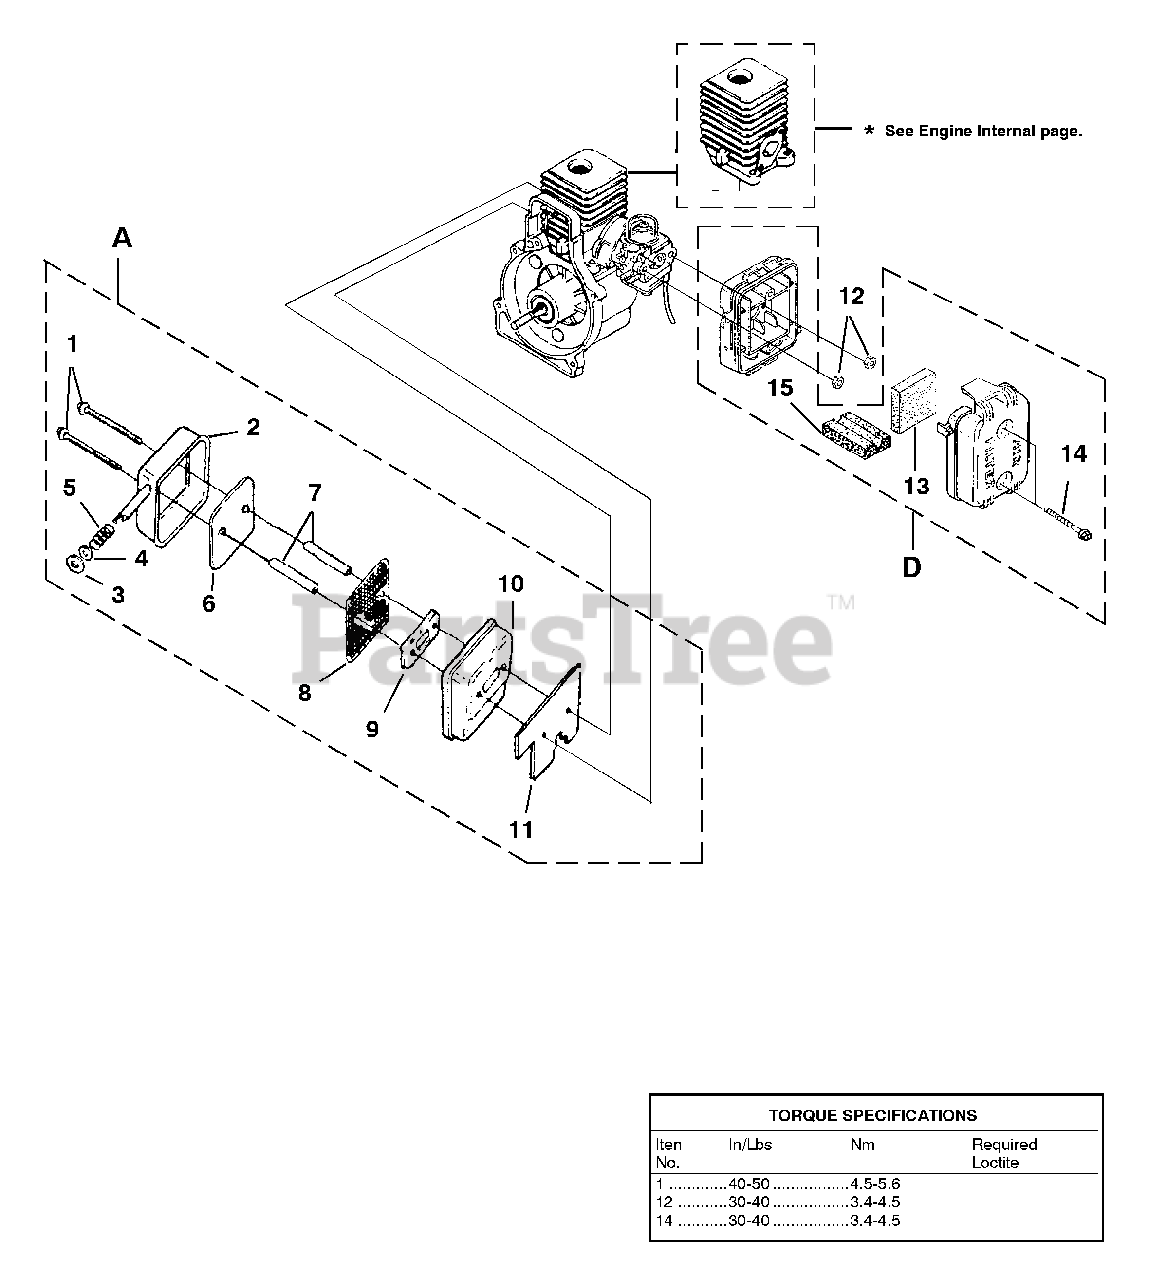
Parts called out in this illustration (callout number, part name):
1	SCREW-Sems Hex Hd. (10-24 x 2 1/2")
2	MUFFLER COVER
3	WASHER-Insulating
4	WASHER-Flat
5	SPRING-Compression
6	DEFLECTOR-Muffler
7	SPACER-Muffler
8	SCREEN-Spark Arrestor
9	PLATE-Reinforcing
10	BODY-Muffler
11	GASKET-Muffler
12	NUT-Hex (10-24)
13	AIR FILTER
14	SCREW-Thd. Form. (#8-16 x 3/4")
15	FILTER, Foam Air
A	MUFFLER-Complete
D	AIR FILTER KIT
